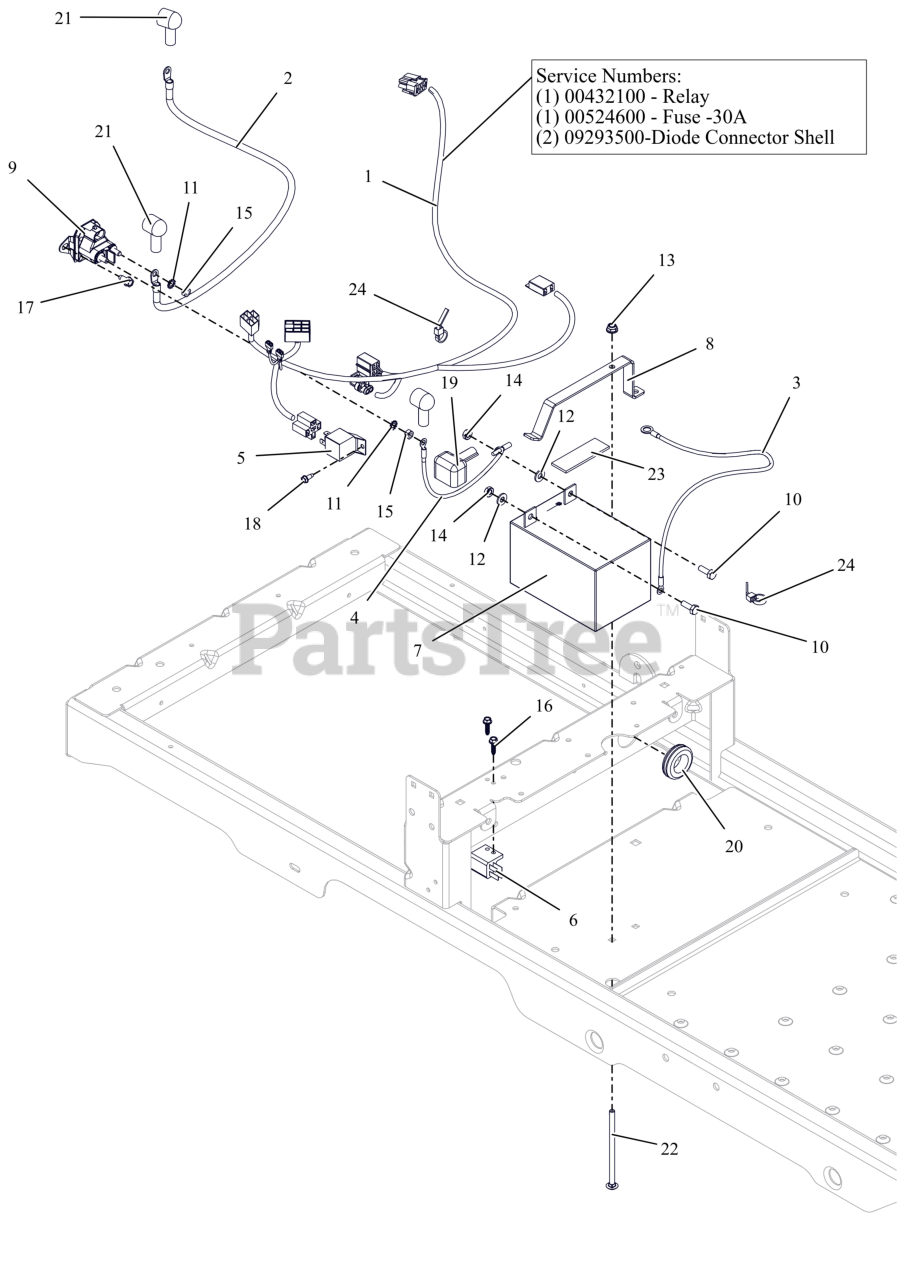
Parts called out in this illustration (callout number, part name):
1	HARNESS, ZOOM / ZT WIRE
1	RELAY,SEALED W/DIODE
1	FUSE, 30 AMP.
1	DIODE, CONNECTOR SHELL
2	CABLE,POS W/(2)1/4 RING 21.5LG
3	CABLE, NEGATIVE 26" 6 GA.
4	CABLE,POS W/2 1/4 RING 15.0 LG
5	RELAY,SEALED W/DIODE
6	SWITCH- DOUBLE POLE N.O./N.O.
7	BATTERY, 12V 12A -190CCA
8	HOLDDOWN, BATTERY, U1&190CCA
9	SOLENOID, STARTER (SEALED)
10	BLT, HEX .25-20X.75 G5 ZCC
11	WSHR,LK-EXT.262X.502X.026 ZCC
12	WSHR,FLT .281X.625X.065 ZCC
13	NUT,NYL-FLG .25-20 GF ZCC
14	NUT-KEPS .250-20 ZCC
15	NUT-STD M6-1.0 ZCC
16	SCR, PLASTITE #12X.75 ZCC
17	SCR-TAP .25-20X.50 HWH ZCC
18	@SCR-TAP 10-24X.50 HWH TR YWZC
19	INSULATOR
20	GROMMET 1.0ID X 1.38 OD
21	BOOT, EYELET TERMINAL
22	BLT, RHSN .25-20X4.50 G5 ZCC
23	PAD,RBR 1.0"X3.0" W/ADHESIVE
24	CABLE TIE LG 5-1/2
